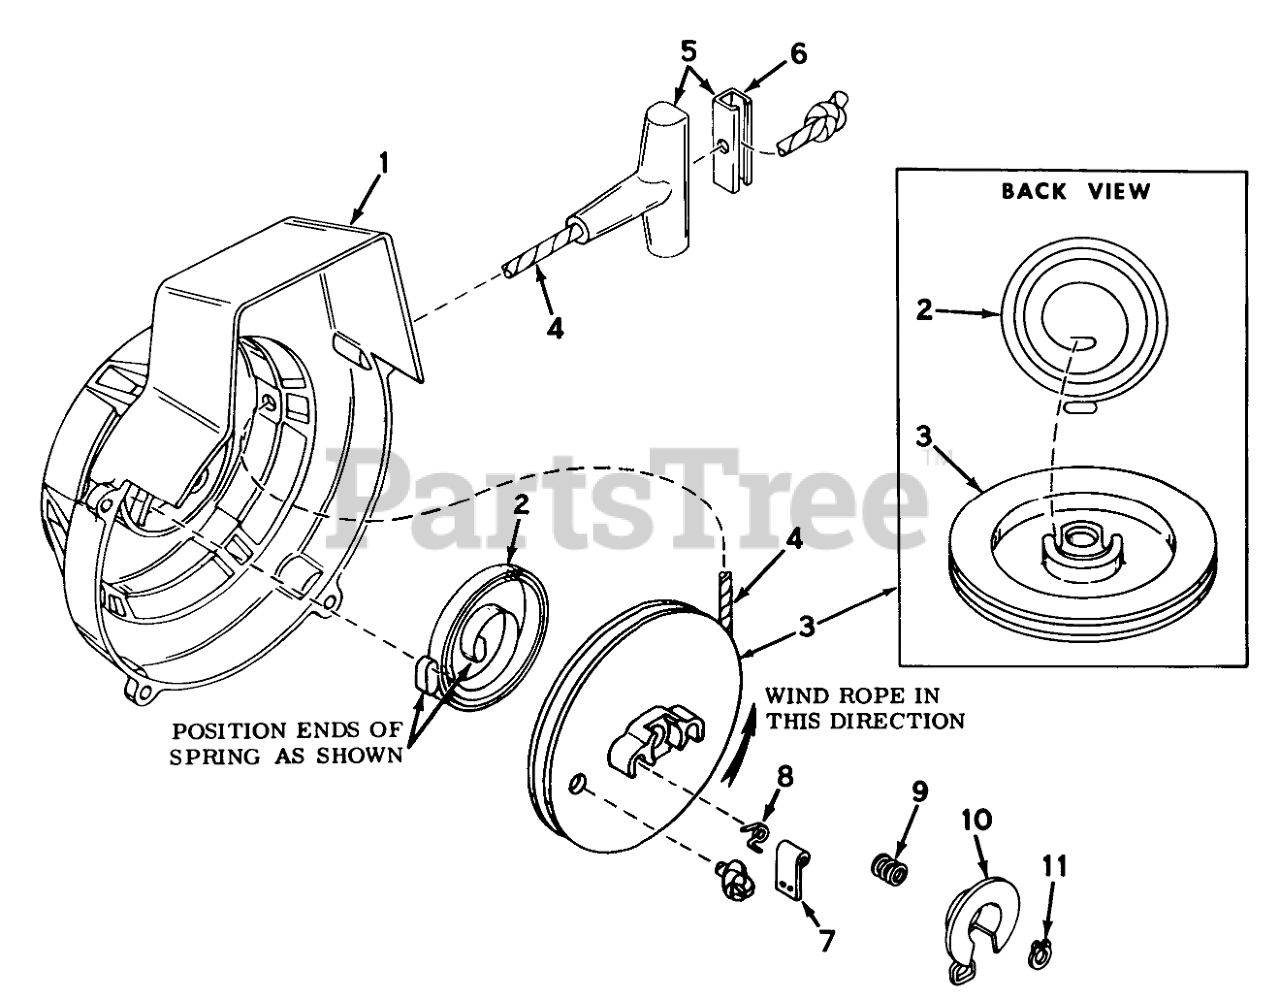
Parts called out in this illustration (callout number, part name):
1	Housing Assy., Shroud & Starter
2	Spring, Rewind
3	Pulley, Starter Rope (Incl. No. 8)
4	Rope-Starter
5	Handle Assembly, Starter Rope (Incl. No. 6)
6	Insert, Handle
7	Dog, Starter
8	Retum Spring, Left Hand Wound
9	Spring, Brake
11	"E" Ring Truarc
